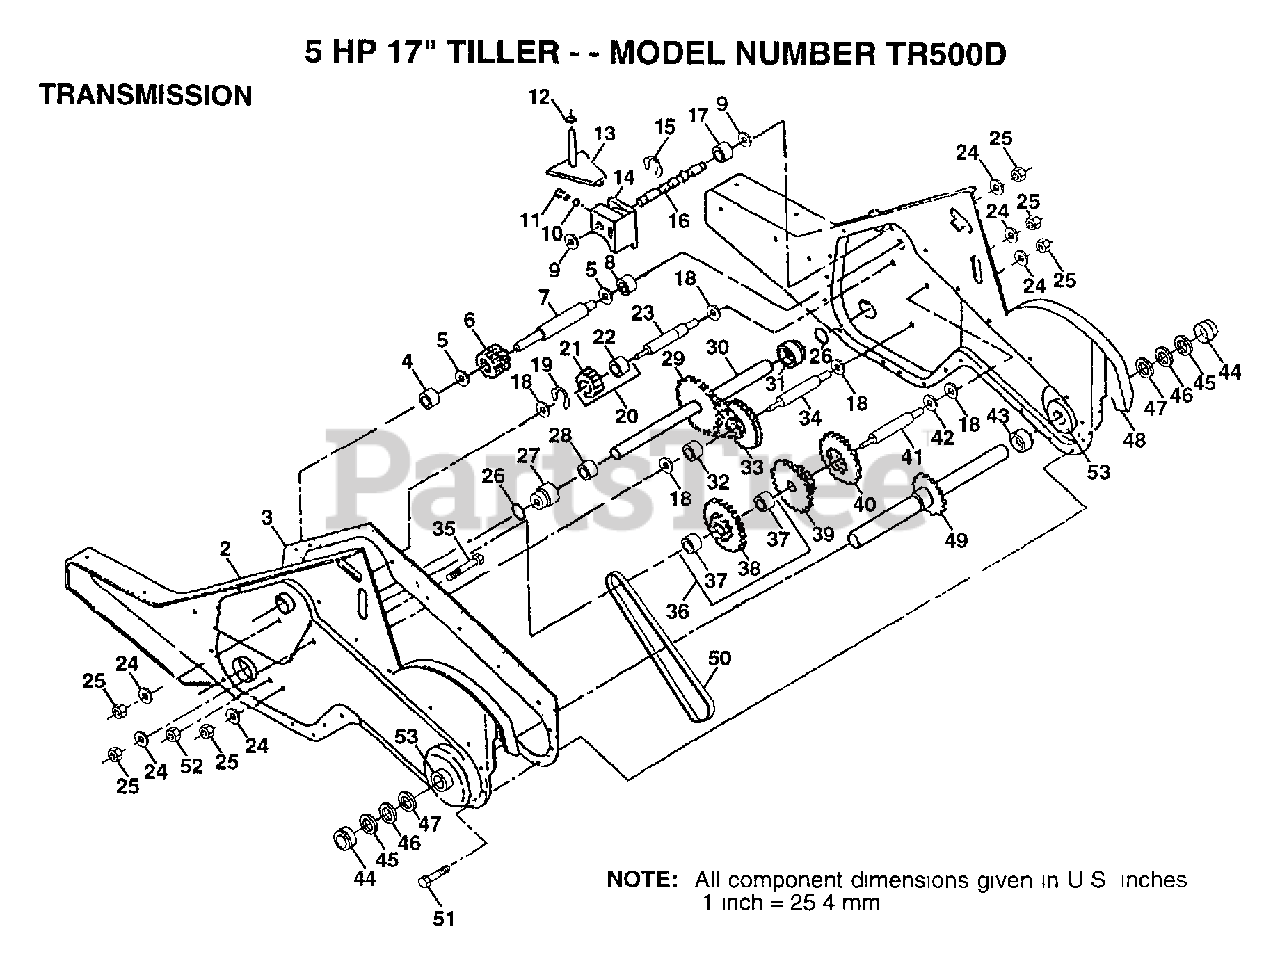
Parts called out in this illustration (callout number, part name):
2	GEARCASE, L.H.
3	GASKET TI
4	NEEDLE BRNG LT
5	"T, BEARING"
6	PINION-INPUT CRT
7	SHAFT-INPUT CRT
8	"TI, BEARING"
9	WASHER SEAL CRT
11	SPRING-SHIFT CRT
12	O-RING TI
13	ARM ASSY CRT
14	SHIFT FORK TI
15	KLIP RING
16	SHAFT SHIFT CRT
17	SPACER SPLIT CRT
18	WASHER
19	KLIP RING
20	GEAR ASSY CRT
21	GEAR-REV IDLR CRT
22	NEEDLE BEARING TI
23	SHAFT CRT
24	LOCKWASHER
25	NUT.ASF.HEX.7/16
26	O RING CRT
27	"CRT, BEARING"
28	BUSHING TI
29	CHAIN CRT
32	SPACER TI
33	SPRCKT 8 GEAR CRT
34	SHFT 2ND RED. CRT
35	SCRW WHIZ LOK CRT
36	SPROCKET ASM.
37	BEARING
39	GEAR TI
40	GEAR TI
41	REDUCTION SHFT TI
42	BRNG RACE
43	SPACER TI
44	CUP.FORMED.
45	RING SPIRAL CRT
46	SEAL RING RUBBER
47	OIL SEAL STD
49	TINE SHAFT
50	CHAIN.50 LINK TI
51	SCREW CRT
52	NUT.HEX.5/16-18
